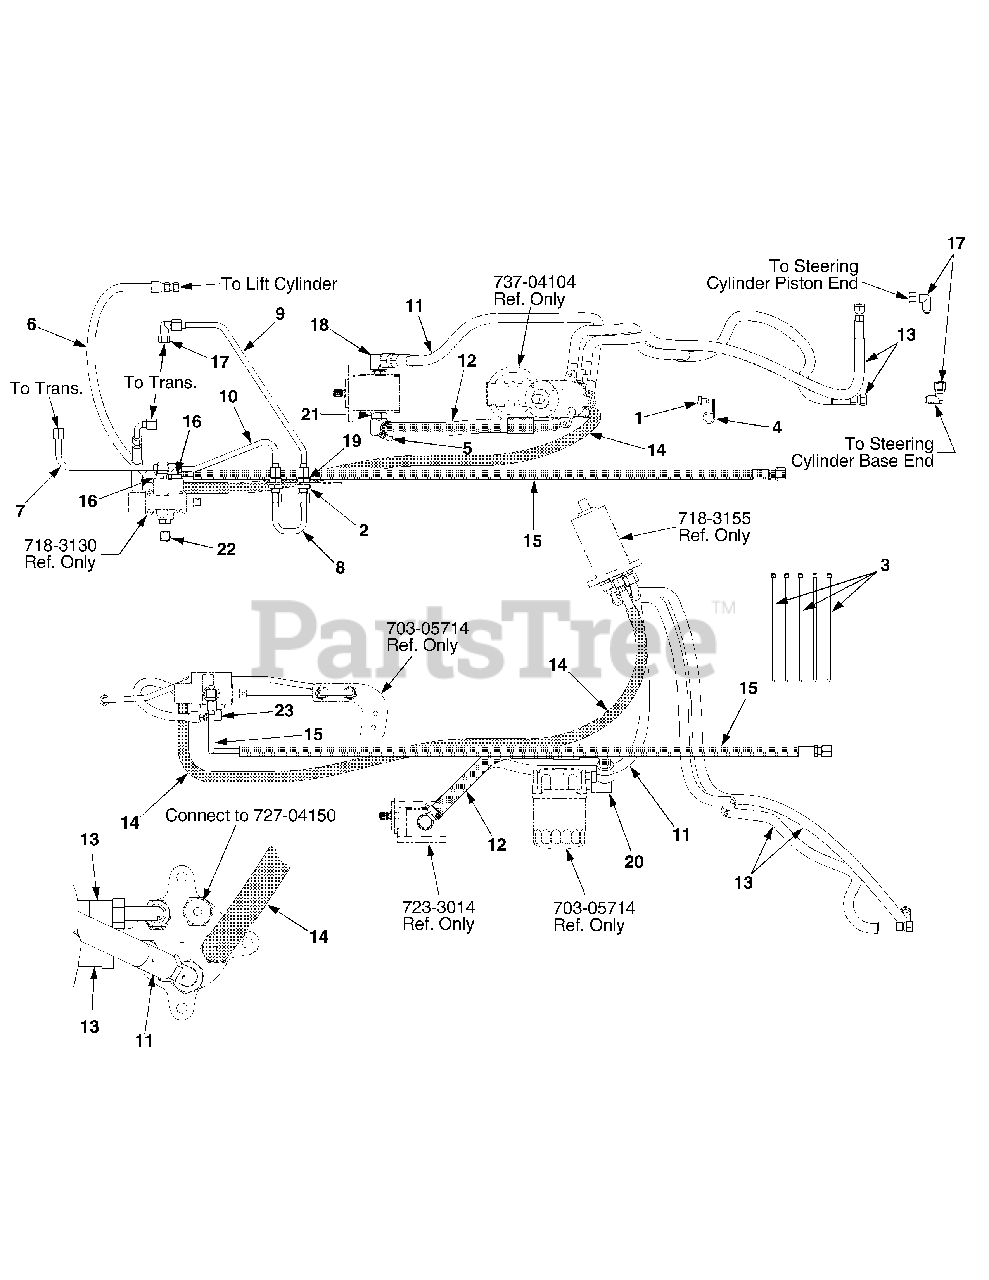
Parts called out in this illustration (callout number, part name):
1	Screw, Hex Wash Hd Tapp, 5/16-18 x .5
2	Nut, Hex Jam, 9/16-18 GR5
3	Tie, Cable
4	Clamp, Hose
5	Clamp, Adjustable Hose
6	Hose, Lift Cylinder
7	Tube, Cylinder Return
8	Tube, U Return
9	Tube, Return Tank
10	Tube, Return
11	Hose, Steering Pressure
12	Hose, Aux. Pump-Filter
13	Hose, Steering
14	Hose, Steering - Tank
15	Hose, Lift Inlet
16	Fitting, 90 Degree
17	Fitting, 90 Degree Swivel
18	Fitting, 90 Degree
19	Fitting, Bulkhead
20	Fitting, 90 Degree
21	Fitting, 10 Orb:5/8 tube
22	Fitting, 90Degree
23	Fitting, 90 Degree
